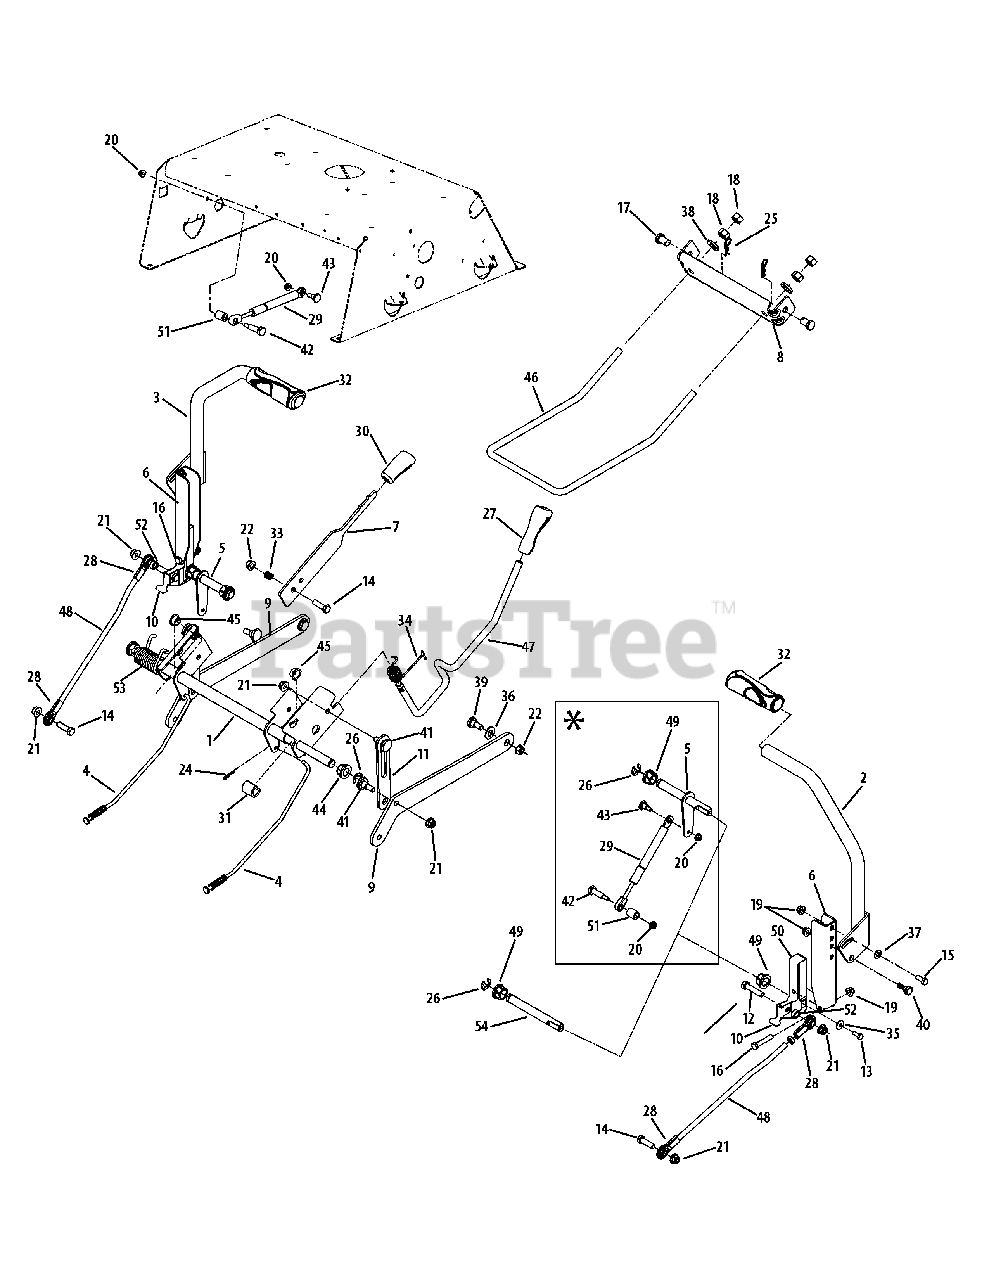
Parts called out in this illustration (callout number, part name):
2	Lever, Lapbar, RH
3	Lever, Lapbar, LH
5	Control Shaft
6	Lapbar Pivot Bracket
8	Front Deck Hanger Bracket
9	Deck Lift Arm
10	Switch Actuator Bracket
12	Hex Screw 3/8-16 x 1.75
13	Hex Bolt 1/4-20 x .625" Lg. Gr. 5
14	Hex Bolt 3/8-16 x 1.25
15	Hex Bolt 5/16-18 x .75" Lg. Gr. 5
16	Hex Screw 5/16-18 x 1.75" Lg.
17	Clevis Pin .50 x .78
18	Hex Nut 1/2-13
19	Hex. Flanged L-Nut 5/16-18 Gr. F,
20	Hex. Flanged L-Nut Hex 1/4-20 Gr.
21	Hex. Flanged L-Nut 3/8-16 Gr. F Ny
22	Hex. Flanged L-Nut 3/8-16 Gr. F
24	Int. Cotter Pin .072 x 1.13" Lg.
25	Cotter Pin
29	Cylinder, Damper
31	Spacer .62 x 1.0
32	Hand Grip
33	Compression Spring
34	Torsion Spring
35	Cupped Washer .265 ID x .75 OD
36	Flat Washer .53 ID x 1.00 OD x .06
37	Flat Washer .34 ID x .688 OD x .065
38	Flat Washer .531 ID x 1.0 OD
39	Shld. Scr. .500 Dia. x .335" Lg.
40	Shoulder Screw
41	Shoulder Screw .50 Dia.
42	Shoulder Screw .375 x 1.16
43	Shoulder Screw .375 x .38:1/4-20
44	Hex Flange Bearing .630 ID
45	Flange Bearing .626 x .938 x .344
46	Deck Front Hanger Rod
47	Deck Lift Handle Rod
48	Lapbar Control Rod
49	Hex Flange Bearing
51	Spacer, .385 x .63 x .75
52	Spacer, .380 x .625 x .265
53	Torsion Spring (50" Deck Only)
54	Control Shaft
